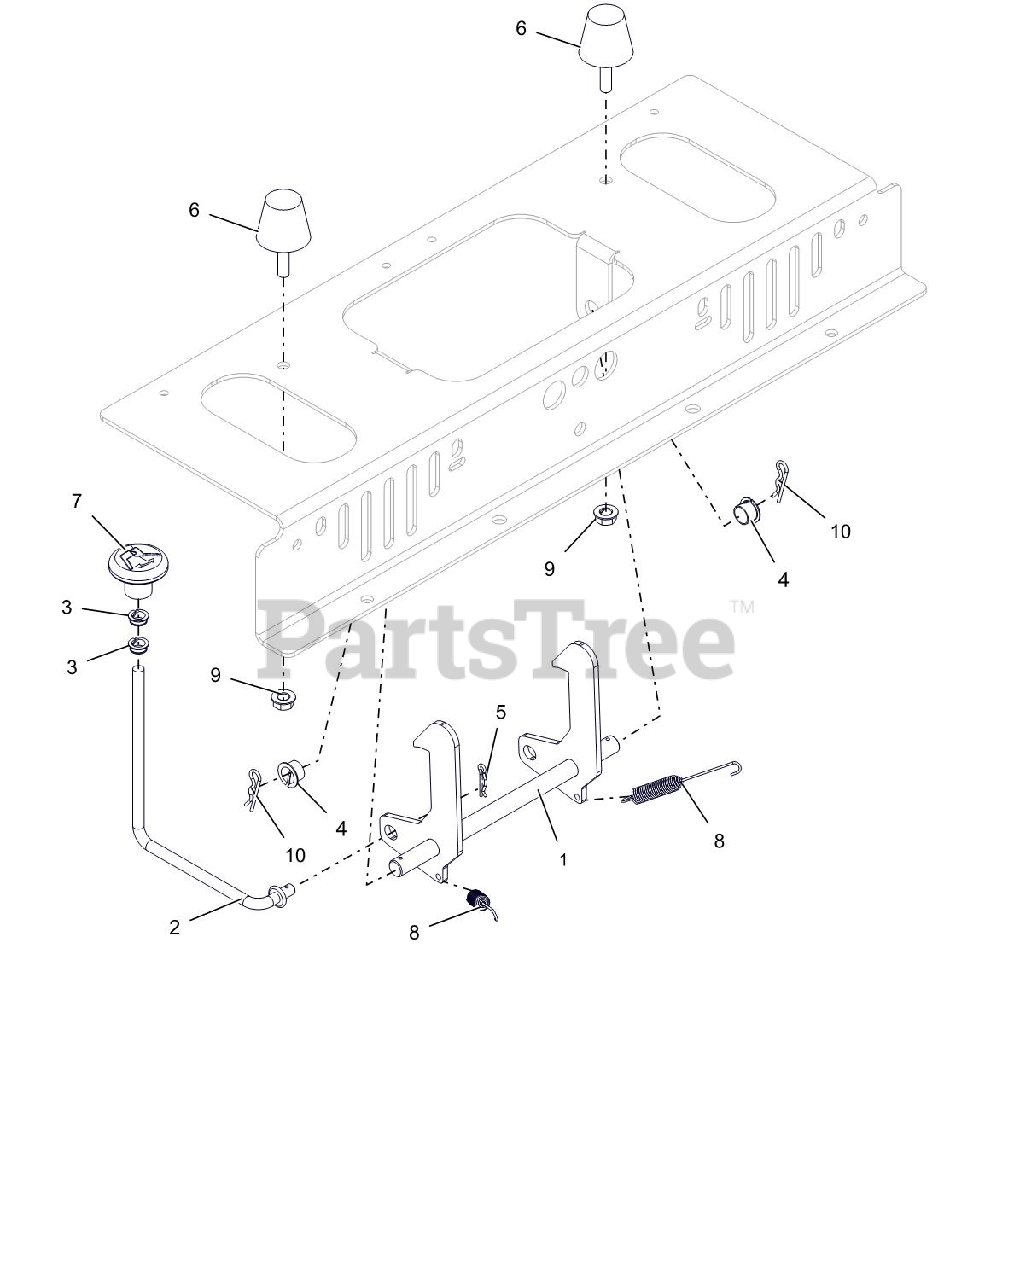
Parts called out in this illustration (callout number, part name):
1	SEAT LATCH WLDMT - LOW FILM
2	LINKAGE, SEAT RELEASE
3	BUSHING, POLYLINER-.38 SNAPIN
4	BUSHING, POLYLINER-.50 SPLIT
5	PIN-HAIR, ENDRIES #25 YWZC
6	BUMPER,STUD MOUNTED CONE SHAPE
7	KNOB, PUSH/PULL
8	SG-TENS .043X.44X3.31 WLD 5.8
9	@NUT-SPNLK-FLG .312-18 YWZC
10	PIN-HAIR INT .08X.38X1.42 YWZC
